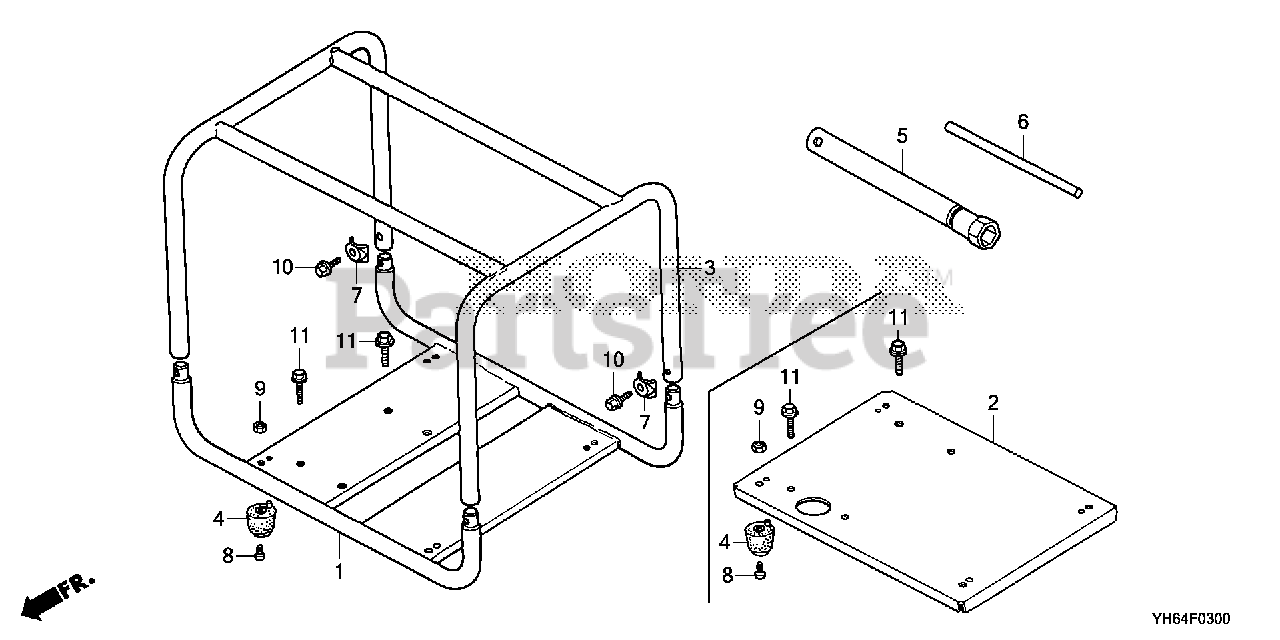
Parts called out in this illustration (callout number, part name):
2	BED, FRAME
4	RUBBER (LOWER)
8	SCREW, PAN (6X10)
9	NUT, HEX. (6MM)
11	BOLT, FLANGE (8X32)
